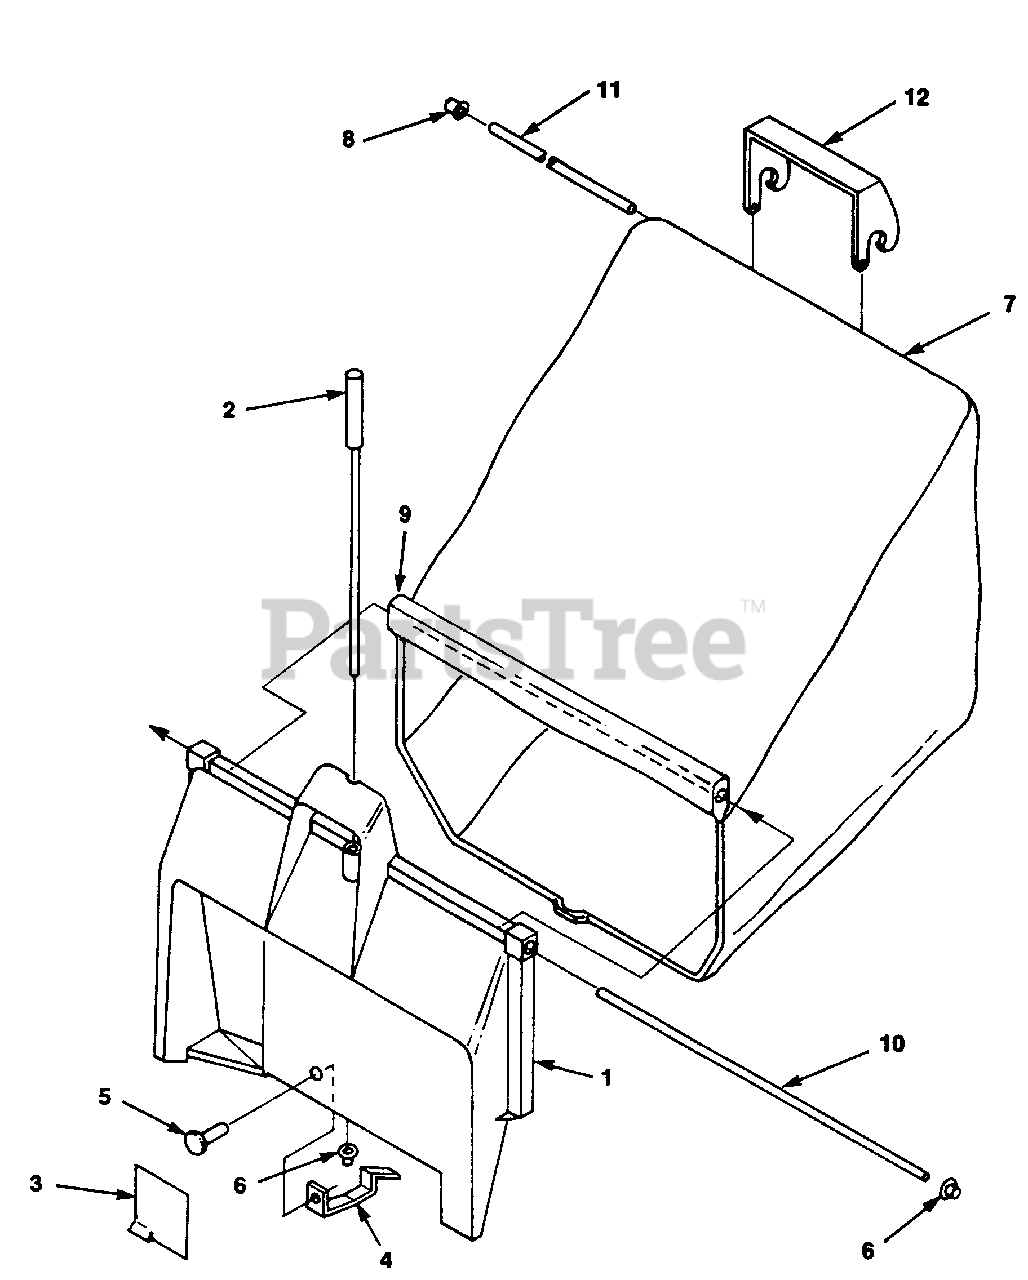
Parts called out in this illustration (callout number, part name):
1	ADAPTER ASSY.
2	ROD-Latch release
3	DEFLECTOR
5	RIVET 5/32 X 3/8"
7	BAG-Replacement
8	RETAINER-Bag rod
9	ROD-Bag support
10	ROD-Bag hinge
12	HANDLE-Bag
